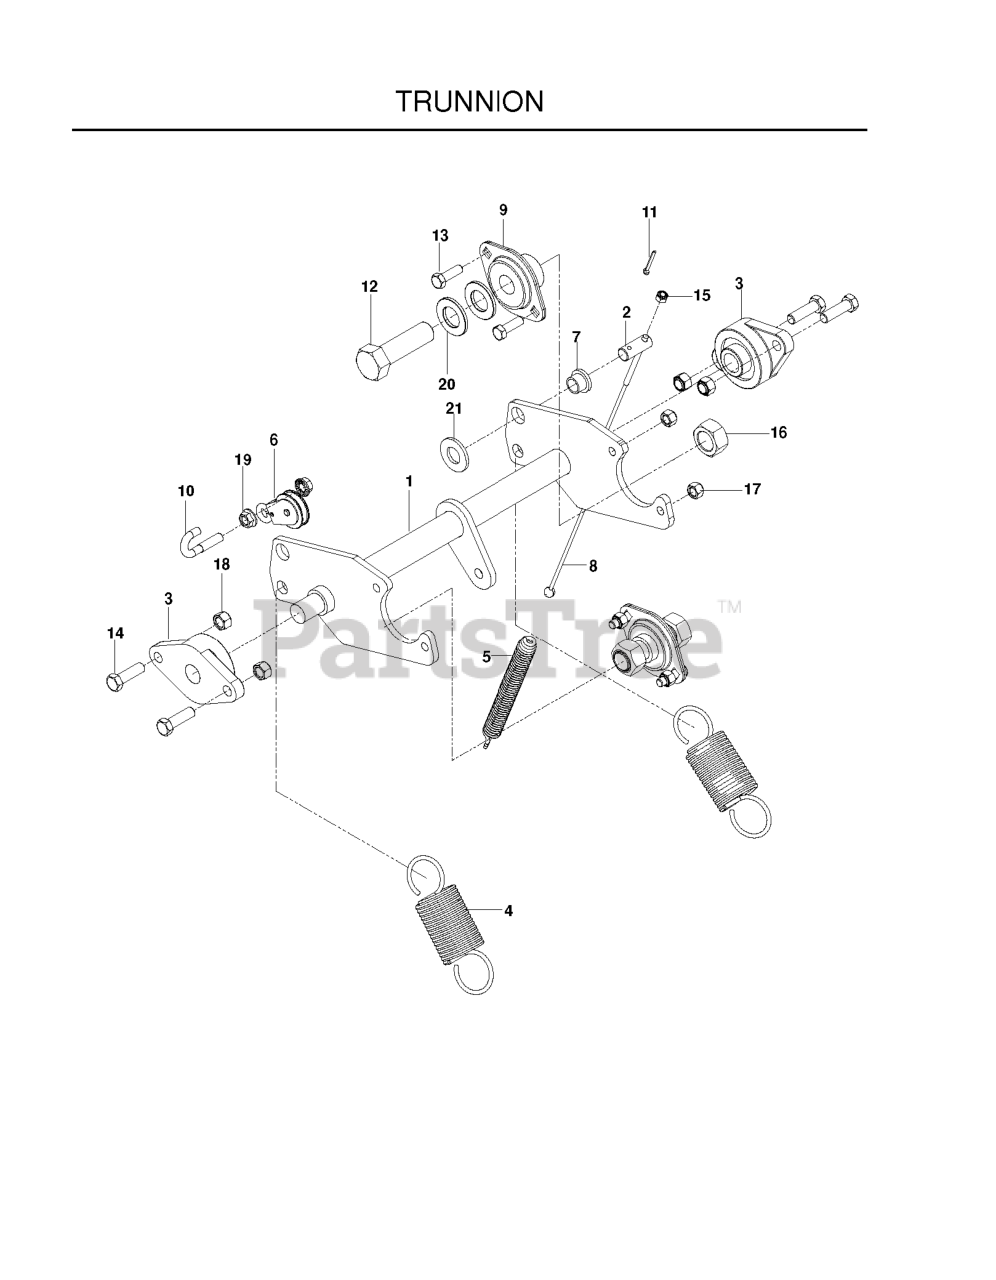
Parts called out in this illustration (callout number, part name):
1	TRUNNION SHAFT, BLACK
2	PIN - CABLE PIVOT
3	BEARING .75-2 BOLT
4	SPRING - EXTENSION
5	SPRING - EXTENSION, CABLE
6	BRACKET, PULLEY
7	BUSHING, FLANGED NYLON
8	CABLE - PULL
9	FLANGE BEARING ZINC PLATED
11	PIN COTTER 1/8 X 1 ZD
12	HCS 3/4-16 X 2-1/2 GR 5 ZD
13	HCS 5/16C X 1
14	HCS 3/8C X 1 1/4 GR5
15	NUT.1/4-20.HEX.NYLOC.ZD
16	NUT 3/4-16 HEX TOP LK ZD
17	NUT 5/16 NYLOC
18	NUT 3/8-16 NYLOC
19	NUT 5/16C WHIZ
20	WASHER 3/4 FLAT SAE ZD
21	WASHER 5/8 FLAT
